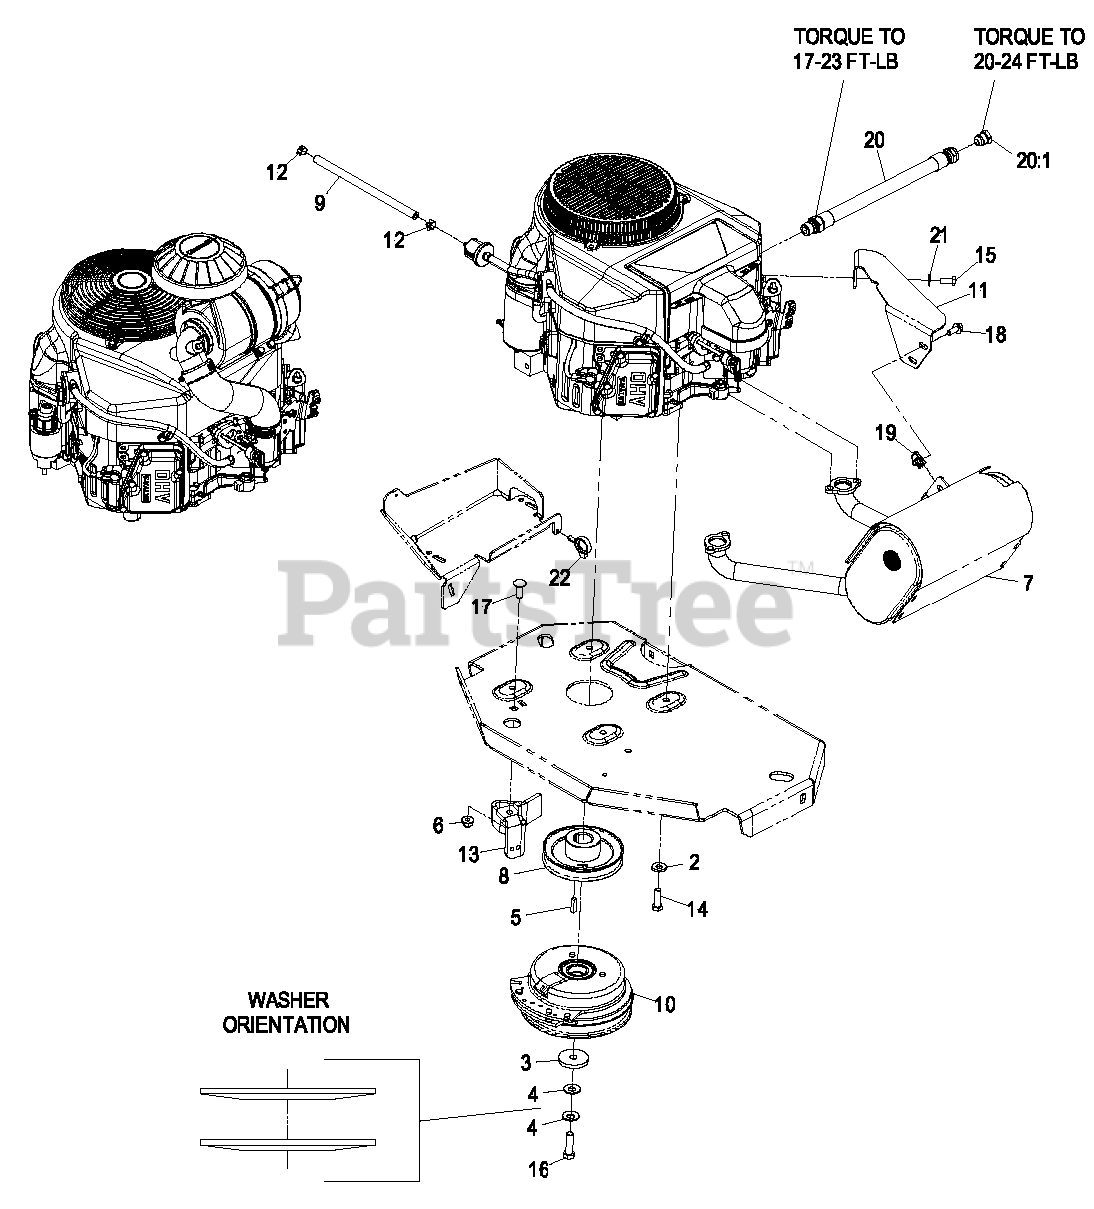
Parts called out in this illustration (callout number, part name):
2	WASHER-BELLEVILLE
3	WASHER-CLUTCH
4	WASHER-SPRING
6	NUT-HF, NI
7	MUFFLER
8	SHEAVE-PUMP, DRIVE
9	HOSE-FUEL
11	BRACKET-MUFFLER
12	CLAMP-HOSE
13	CLUTCH-ANCHOR
14	SCREW-HH
15	SCREW-HH
16	SCREW-HH 7/16-20 X 1 1/2 W/LOCTITE
17	SCREW-CARR
18	SCREW-HHF
21	WASHER-SPRING
22	CLAMP-HOSE
